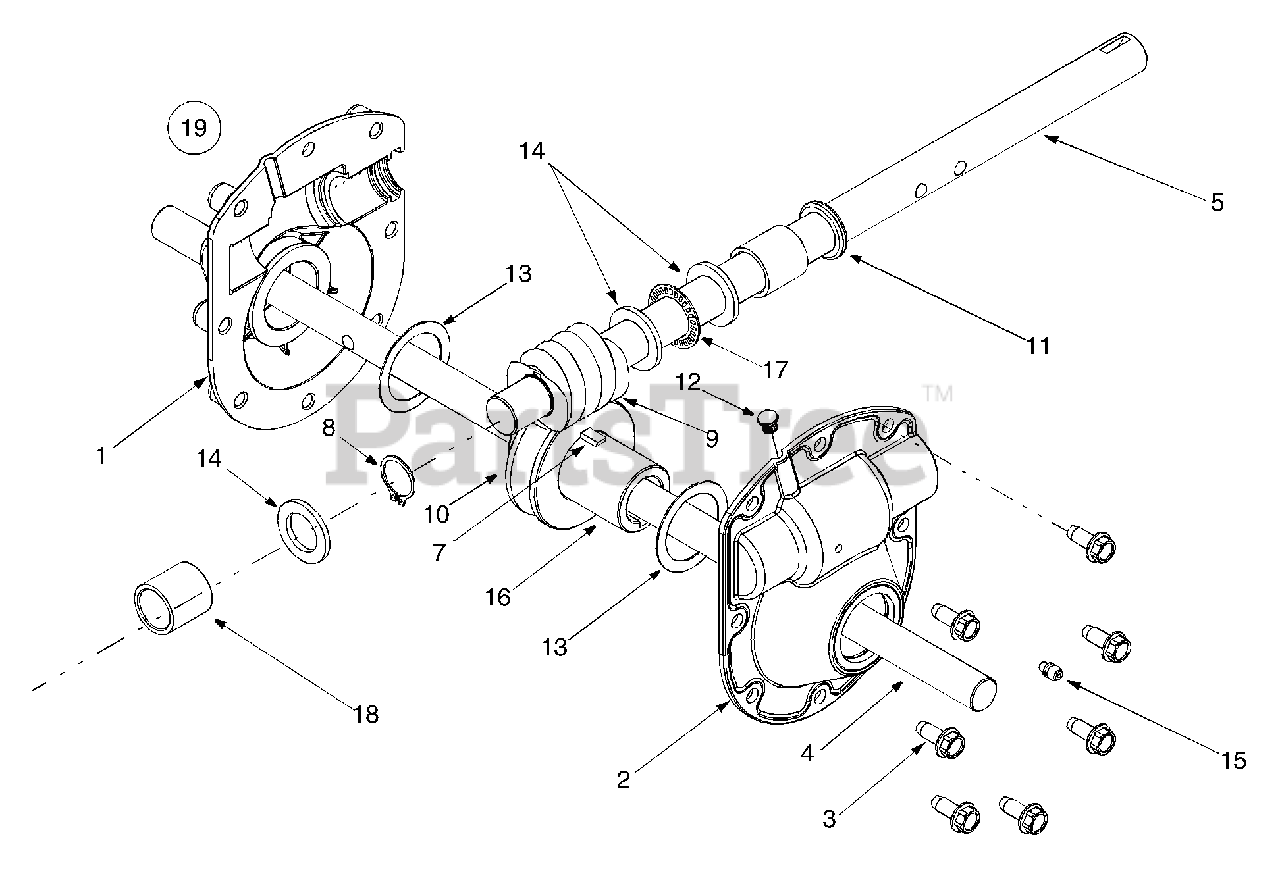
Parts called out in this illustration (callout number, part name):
1	Housing Assembly, RH
2	Housing Assembly, LH
3	Screw, 5/16-18 x 0.75
4	Spiral Axle
5	Auger Drive Shaft
7	#91 Woodruff Key 1/4 x 3/4
8	Snap Ring.875 Dia.
9	Double Thread Worm Gear LH
10	Worm Gear, LH
11	Oil Seal.875 ID
12	Plug, 1/4 x.437
13	Flat Washer, 1.52 x 2.0
14	Flat Washer,.88 x 1.38
15	Lube Fitting, 3/16 Drive
16	Worm Gear Shaft
17	Thrust Bearing.877 ID
18	Sleeve Bearing,.877 x.125 x 1.11
19	Auger Gearbox Assembly Complete
